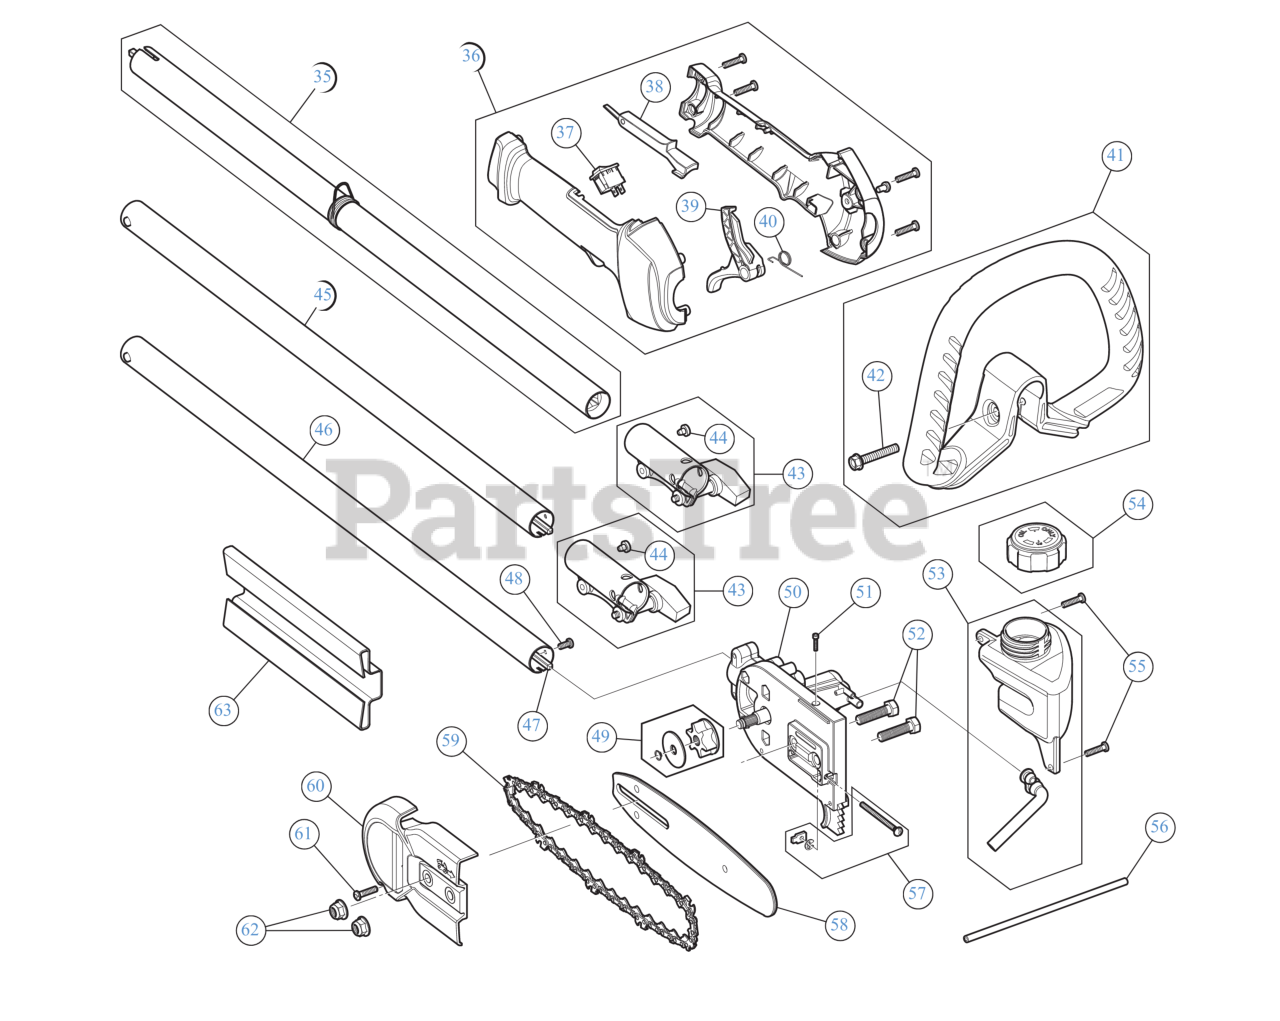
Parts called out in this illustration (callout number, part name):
35	BOOM ASSEMBLY UPR
36	THROTTLE GRIP ASSEMBLY
37	SW, MOMENTARY ON/O
38	LEVER LOCK OUT
39	THROTTLE TRIGGER
40	SPRING TRIG
41	HANDLE ASSEMBLY
42	BOLT 1/4-20X1 1/2
43	COUPLER ASSEMBLY
44	SCREW, 10-32X.250 TA
45	EXTENSION BOOM ASSEMBLY
46	BOOM ASSEMBLY 24"
47	LOWERIBLE DRIVE SHAFT
48	SCREW 1/4-20 X.500
49	SPROCKET ASSEMBLY
50	GEAR BOX ASSEMBLY
51	SCREW 4X40X.50
52	SCREW 5/16-18 x 1.25 GR5
53	OIL TANK ASSEMBLY
54	FUEL CAP ASSEMBLY
55	SCREW, #8-16X.750 PH
56	OIL LINE
57	CHAIN TENSION HDW
58	BAR 10"
59	CHAIN 10"
60	CHAIN GUARD
61	SCREW, #8-16X.750 PH
62	FLANGE LOCK NUT 5/16-18
63	SCABBARD CHAIN GUARD
